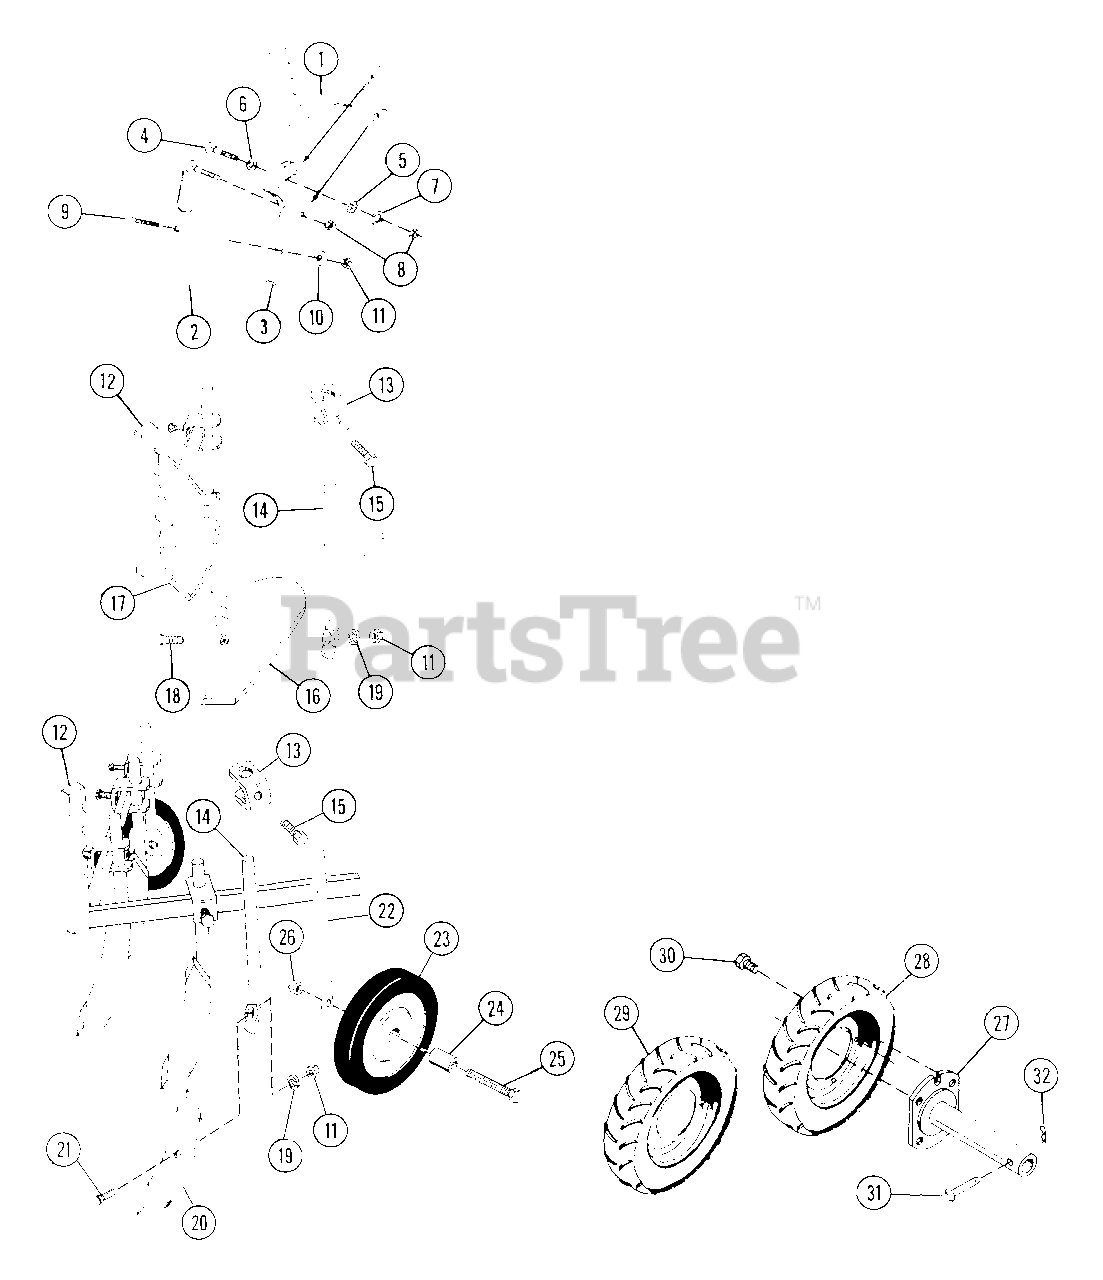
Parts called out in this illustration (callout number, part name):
1	TOOL BAR
2	FURROWER
3	TOOL HOLDER
4	BLT-RDHDSQNK .44-14X2.00 PL
5	WSHR-LK-EXT .500X.040 MED
6	WSHR-LK-EXT .625X.045
7	WSHR-FL-STL .469X.937X.065 PL
8	@NUT-HEX .44-14 YWZC
9	BLT-PLOW .38-16X2.50
10	WSHR-FL-STL .38X.875X.083 PL
11	NUT-HEX .375-16
12	MOUNTING BAR
13	ADJUSTMENT BRACKET
14	STANDARD
15	BLT-HEX .50-13X1.00 PL GR2
16	L H TURN SHOVEL
17	R H TURN SHOVEL
18	BLT-PLOW .38-16X1.50
19	WSHR-LK .375X.094 MED PL
20	SHOVEL REVERSIBLE
21	BLT-PLOW .38-16X1.25 GR5 PL
22	WHEEL SHANK
24	WHEEL BUSHING
25	BLT-HEX .38-16X3.00 PL GR2
26	NUT-LK-CTR .375-16 GR A PL
27	WHEEL HUB
28	L H TIRE AND RIM ASSY
29	R H TIRE AND RIM ASSY
30	BLT-WHL .50-20X.75 GR5 PL
31	CLEVIS PIN
32	PIN-HAIR INT .08X.38X1.42 YWZC
